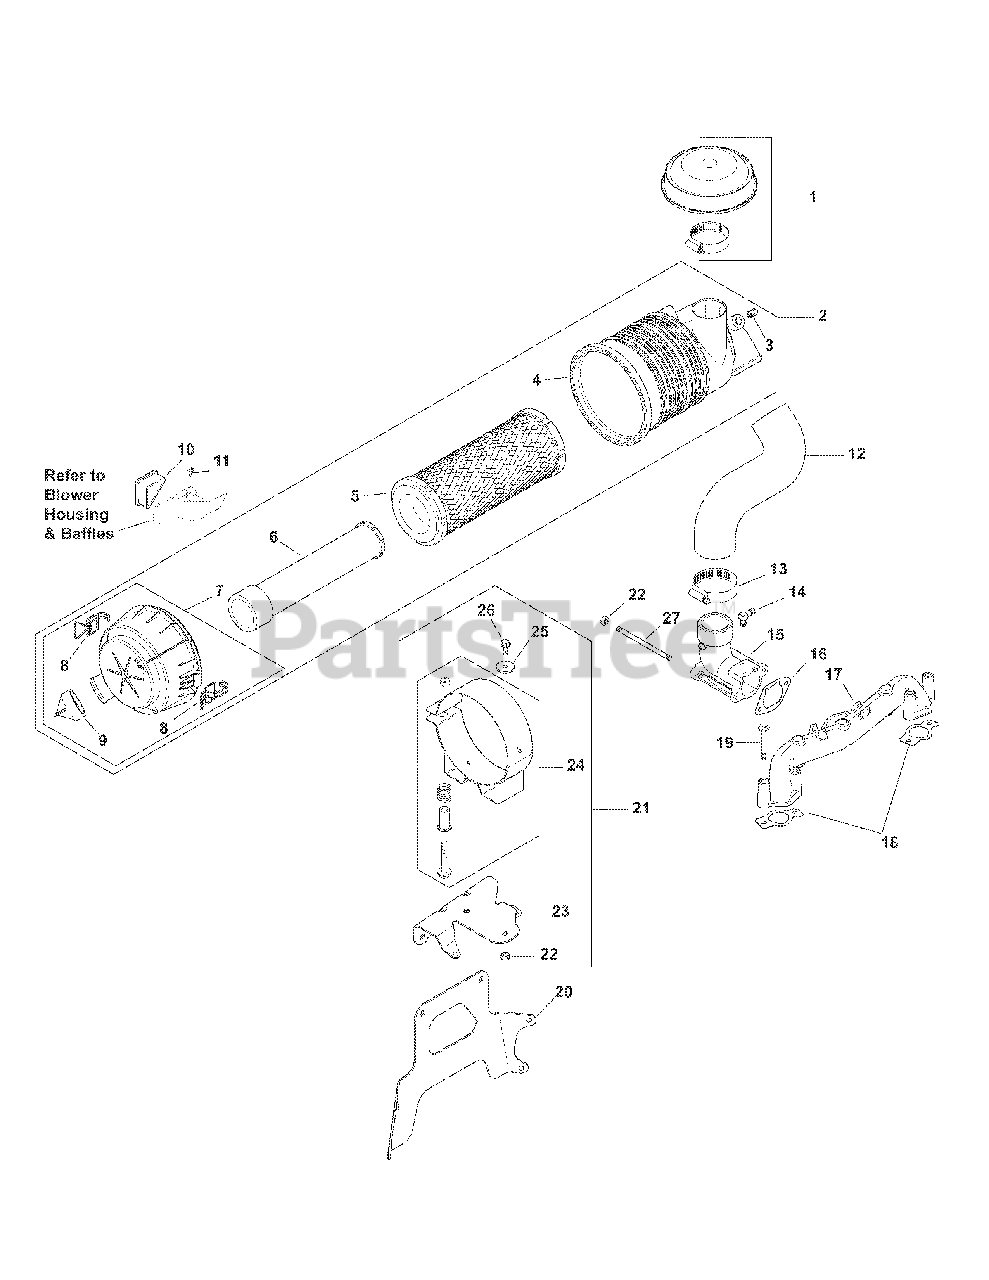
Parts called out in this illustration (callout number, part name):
1	Hood, air cleaner
4	Housing, heavy duty air cleaner
5	Element, air filter-primary
6	Element, air filter-safety
7	Cover assembly, plastic air cleaner (Includes 8,9)
8	Clip
9	Valve, dust ejector
10	Cover, blower housing
11	Screw, wsh hd tp #10-16x1/2 inch
12	Hose, air cleaner
13	Clamp, hose
14	Connector, hose
15	Elbow, air cleaner base
16	Gasket, air cleaner base elbow
17	Manifold, intake
18	Gasket, intake manifold
19	Screw, flg M6x1.0x55
20	Bracket, main support
22	Nut, lock M6x1.0
23	Bracket, air cleaner mtg
24	Bracket assembly, air cleaner
25	Washer, flat 1/4 inch
26	Screw, flg M6x1.0x16
27	Stud M6x1.0x180
